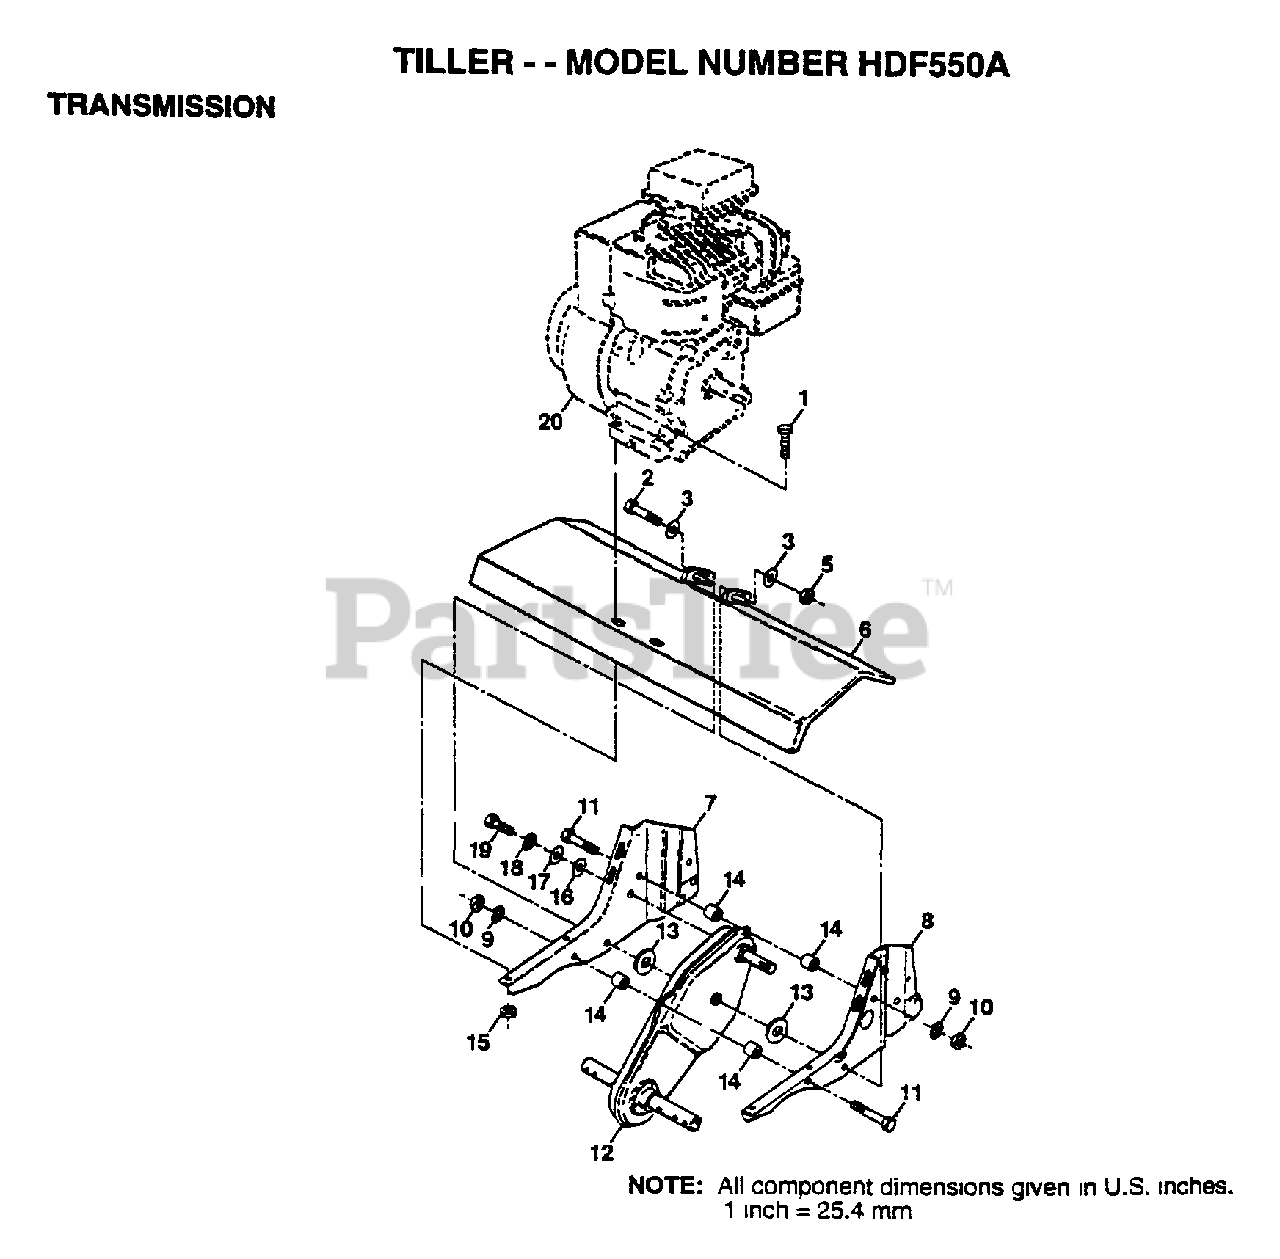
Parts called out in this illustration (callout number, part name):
1	BOLT.HEX.5/16-1.5
2	BOLT HEX 3/8-16
3	WASHER
5	NUT
9	LOCKWASHER
10	NUT.HEX.5/16-18
14	SPLIT SPACER RT
16	WASHER
17	WASHER
18	LOCKWASHER
19	BOLT
